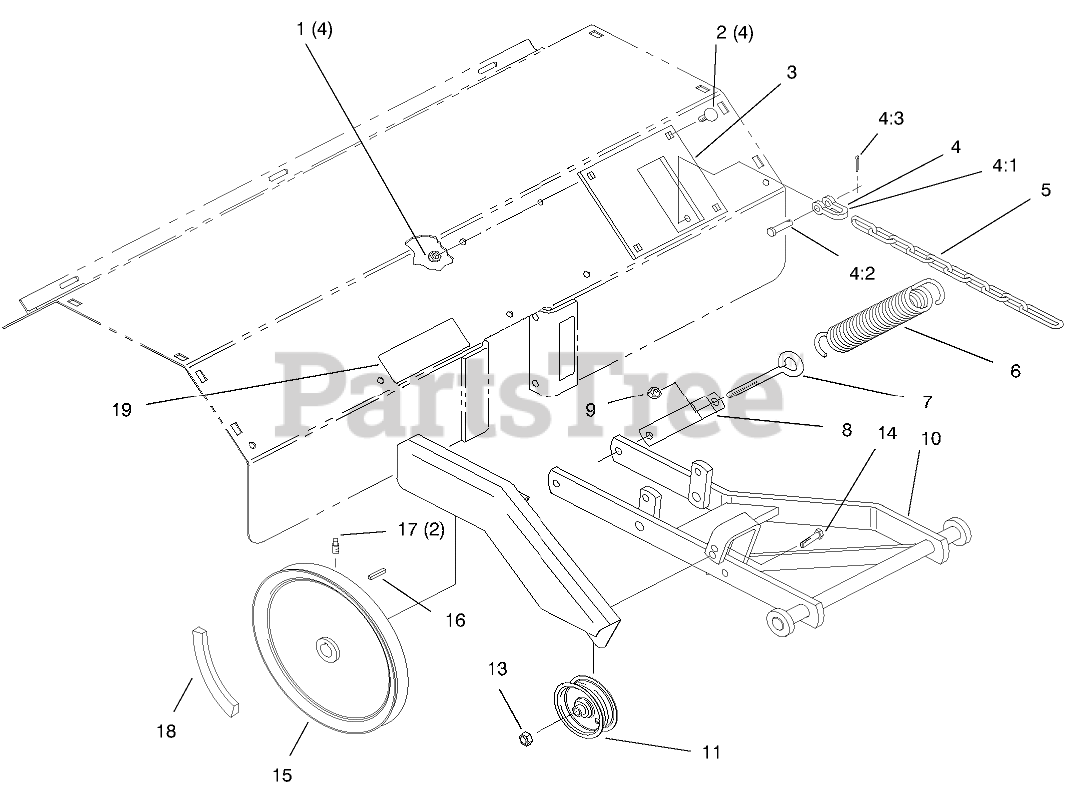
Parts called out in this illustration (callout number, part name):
1	NUT-LOCK, NI
2	BOLT-CARR
3	HITCH ASM
4	Clevis & Pins Asm (Incl. Ref.,4:1,4:2,4:3)
4:1	Clevis
4:2	Clevis Pin
4:3	PIN-COTTER
5	CHAIN LIFT
6	SPRING
7	EYEBOLT
8	BRACKET - SPRING RED
9	NUT-LOCK, NI
10	Hitch
11	PULLEY-IDLER
13	NUT-HEX
15	PULLEY
16	KEY-STRAIGHT
17	SCREW-SQH
18	V-BELT
